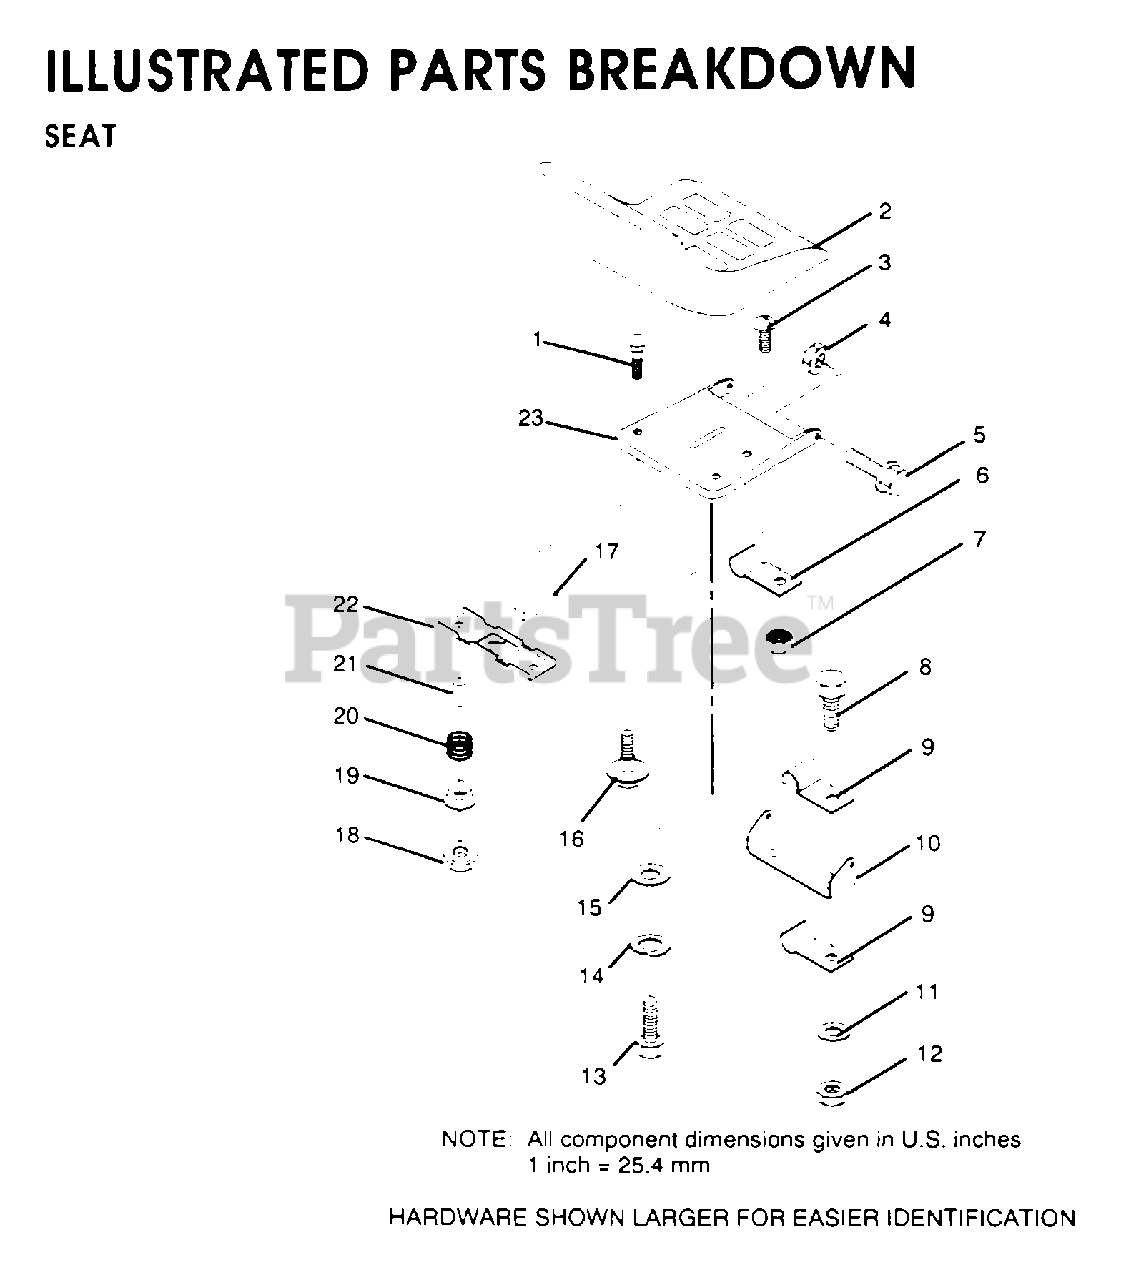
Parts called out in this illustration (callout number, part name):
1	BOLT
7	"NUT,KEPS"
9	"CLIP,INSULATOR"
11	WASHER
13	BOLT
14	LOCKWASHER
15	WASHER
16	"BOLT,SHOULDER"
17	STRIP FORM
19	BUSHING
20	SPRING
21	SPACER SPLIT
22	BRKT SWITCH
